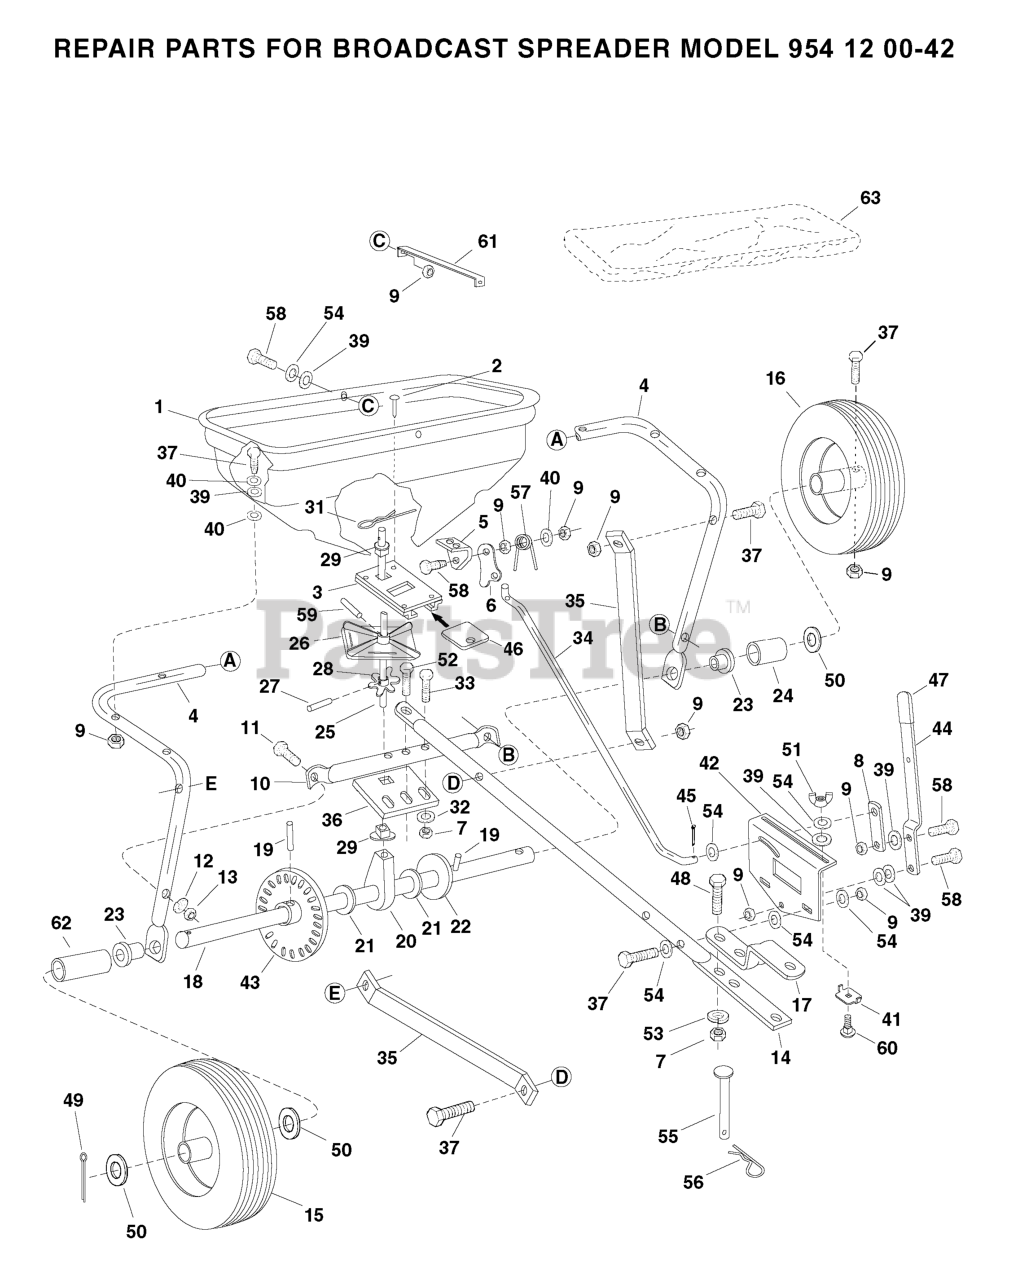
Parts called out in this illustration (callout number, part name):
11	SCREW
16	WHEEL CPL.
17	Bracket, Hitch
19	SPRING PIN
27	PIN RETAINING SCREW
32	WASHER
39	WASHER, NYLON
40	WASHER - M6
43	GEAR, ASSY
46	PLATE, CLOSURE
48	HEX BOLT
53	Spring Washer
58	SCREW M6S 6X20
59	SPRING PIN
